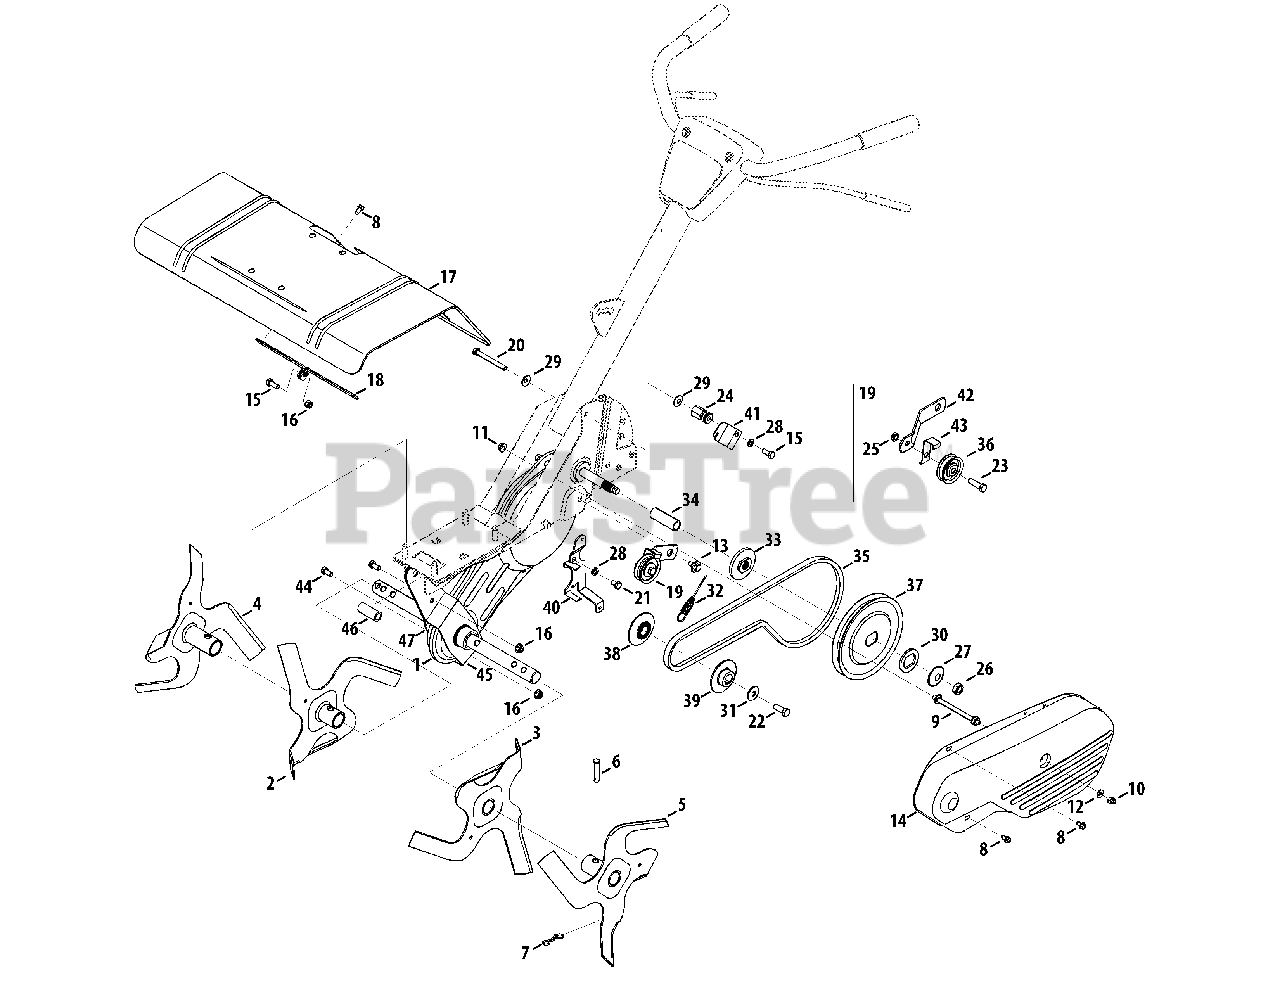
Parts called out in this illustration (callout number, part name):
1	Chain Case Assembly
2	Inner Tine Assembly, RH
3	Inner Tine Assembly, LH
4	Outer Tine Assembly, RH
5	Outer Tine Assembly, LH
6	Clevis Pin, .375 x 1.75
7	Bow Tie Cotter Pin
8	Screw, 1/4-20 x 0.500
9	Bolt, Belt Cover
10	Nut, 1/4-28, Lock
11	Nut, 5/16-18, Flange Lock
12	Flat Washer, .271 x .630 x .065
13	Shoulder Screw, .560 x .165 5/16-18
15	Hex Head Screw, 5/16-18 x .75
16	Nut, 5/16-18, Flange Lock
18	Bracket, Tine Shield
19	Idler Bracket Assembly
20	Hex Head Screw, 5/16-18 x 3.00
21	Hex Head Screw, 5/16-24 x .625
22	Hex Head Screw, 3/8-24 x 1.00
23	Hex Head Screw, 3/8-16 x 1.25
24	Hex Nut, 5/16-18
25	Jamlock Nut, 3/8-16
26	Nut, 1/2-20, Jam
27	Washer, .531 x 1.62 x .045
28	Lock Washer, 5/16
29	Bell Washer, .340 x .872 x .060
30	Flat Washer, 1.26 x 1.87 x .150
31	Bell Washer, .396 x 1.140 x .095
32	Forward Clutch Cable
33	Pulley Adaptor
34	Spacer, .64 ID x 2.4
35	Belt, 4L x 41.9 LG
36	Pulley 1.88 OD
37	Pulley 6.00 OD
38	Inner Engine Pulley
39	Outer Engine Pulley
40	Belt Keeper Bracket
41	Cable Guide Bracket
42	Idler Bracket
43	Belt Keeper
44	Hex Head Screw, 5/16-18 x .625
45	Bracket, Chain Case, LH
46	Spacer, .505 ID x .75 OD x 1.75
47	Bracket, Chain Case, RH
